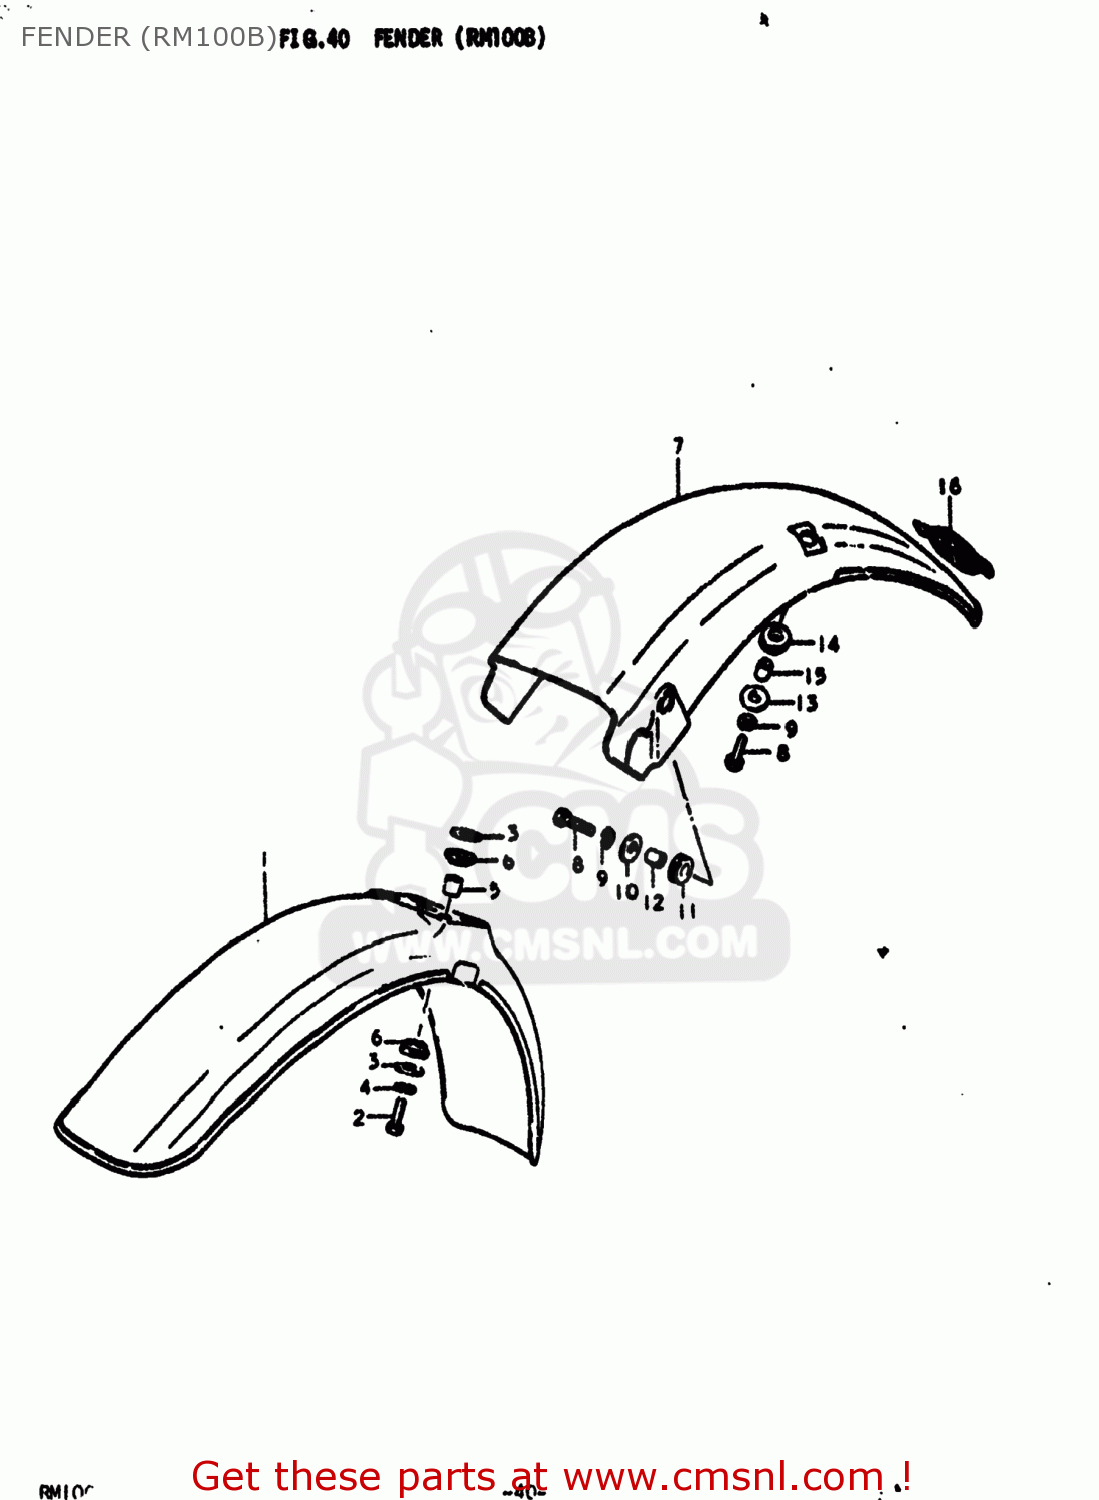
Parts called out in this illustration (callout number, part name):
1	FENDER,FRONT
2	BOLT
3	WASHER (6.5X20X1.2)
4	LOCK WASHER
5	SPACER (6.8X10X10)
6	CUSHION
7	FENDER,REAR
8	BOLT
9	LOCK WASHER
10	WASHER (6.5X20X1.2)
11	CUSHION
12	SPACER(6.1X9X7.5)
13	WASHER (6.5X24X1.6)
14	CUSHION
15	SPACER
